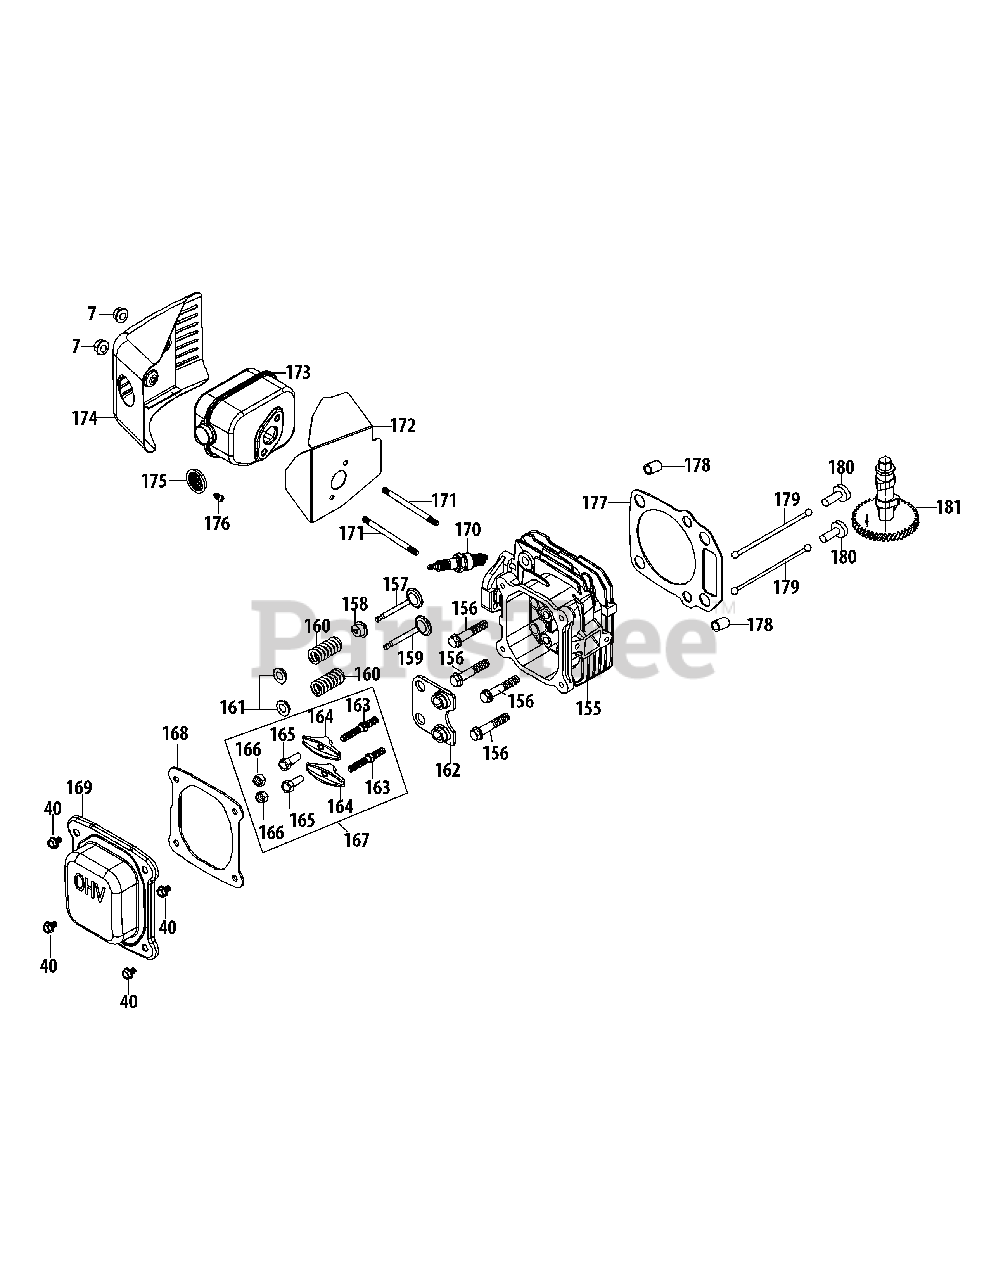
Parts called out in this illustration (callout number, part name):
7	Nut M6 X 10 Mm
40	Bolt M6×14
155	Cylinder Head Assembly
156	Head Bolt M8×54
157	Valve Kit
158	Intake Valve Seal
159	Valve Kit
160	Valve Spring
161	Valve Spring Retainer
162	Push Rod Guide
163	Rocker Arm Stud
164	Rocker Arm
165	Fulcrum Nut
166	Jam Nut
167	Rocker Arm Assembly
168	Valve Cover Gasket
169	Valve Cover
170	Spark Plug
171	Muffler Stud M6×95
171	Muffler Stud Assemlby
172	Muffler Gasket/Heat Shield
173	Muffler
174	Muffler Guard
175	Spark Arrestor
176	Self-Tapping Screw M3.5×9.5
177	Cylinder Head Gasket
178	Dowel Pin 10×16
179	Push Rod Kit
180	Tappet
181	Camshaft Assembly
